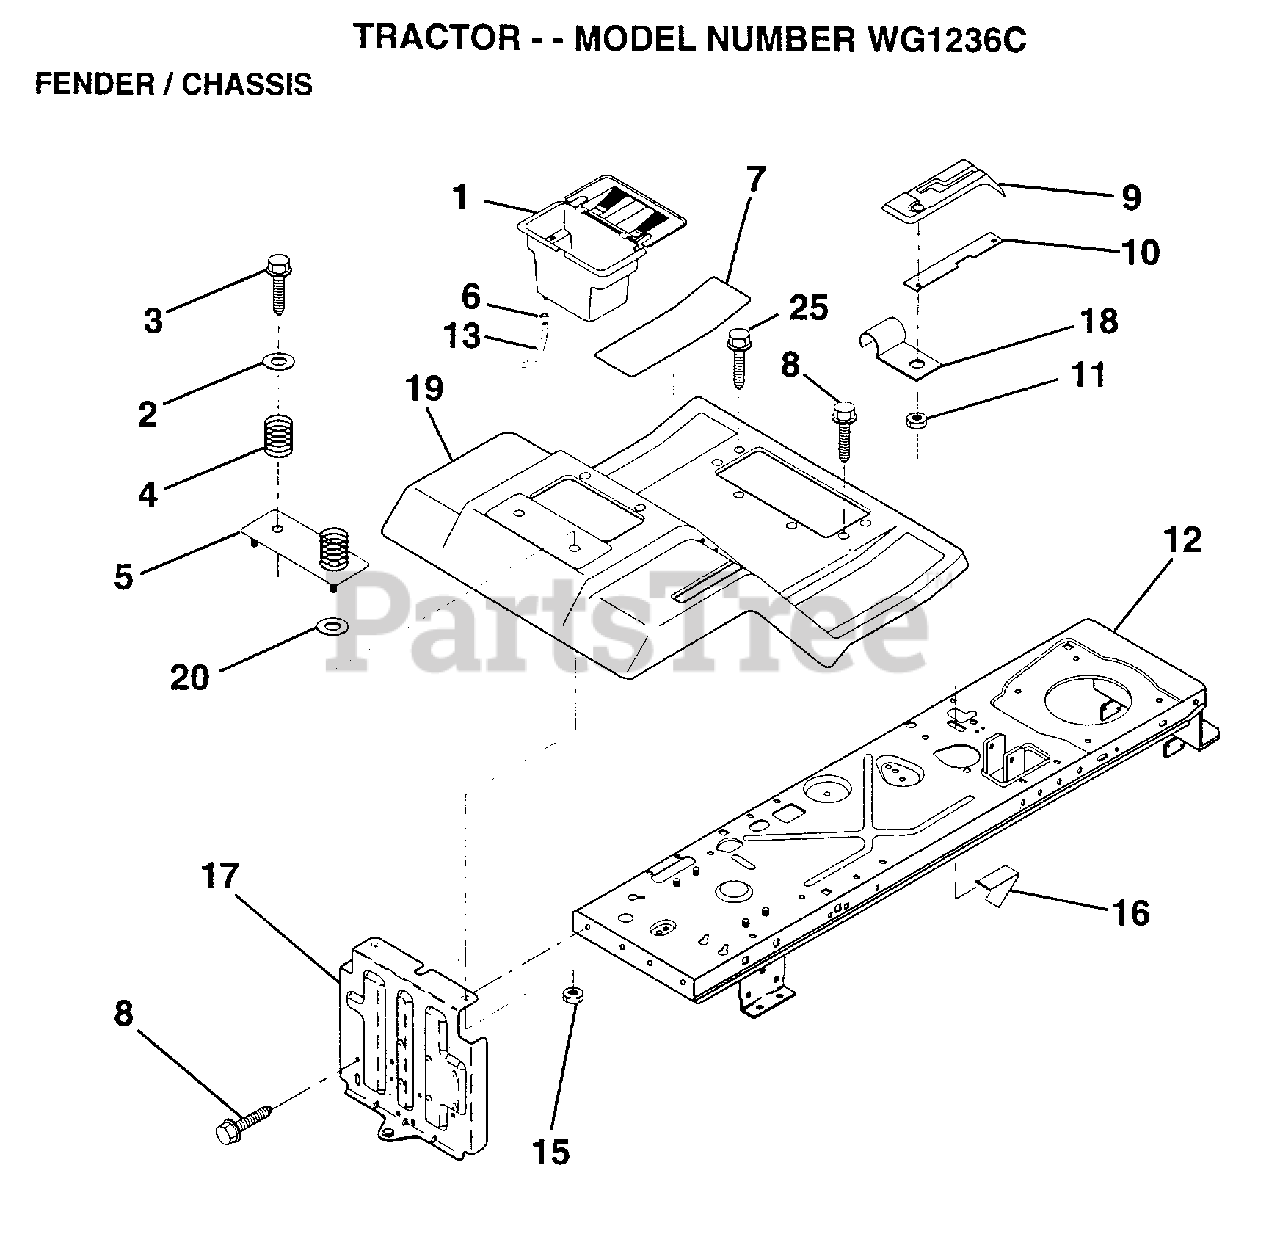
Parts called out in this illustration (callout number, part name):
2	WASHER
3	SCREW
4	SPRING COMPRESSIO
5	PLATE.FEND.LR.ASM
6	HOSE CLAMP T
7	PAD FOOTREST
8	SCREW
10	PLATE LOCK SHIFT
11	NUT
12	CHASSIS.WELD.ASM.
13	TUBE T
15	NUT HXKEP 1/4X20
17	DRAWBAR ASM LR
18	"CLIP,INSULATOR"
19	FENDER/FOOTREST
25	SCREW
